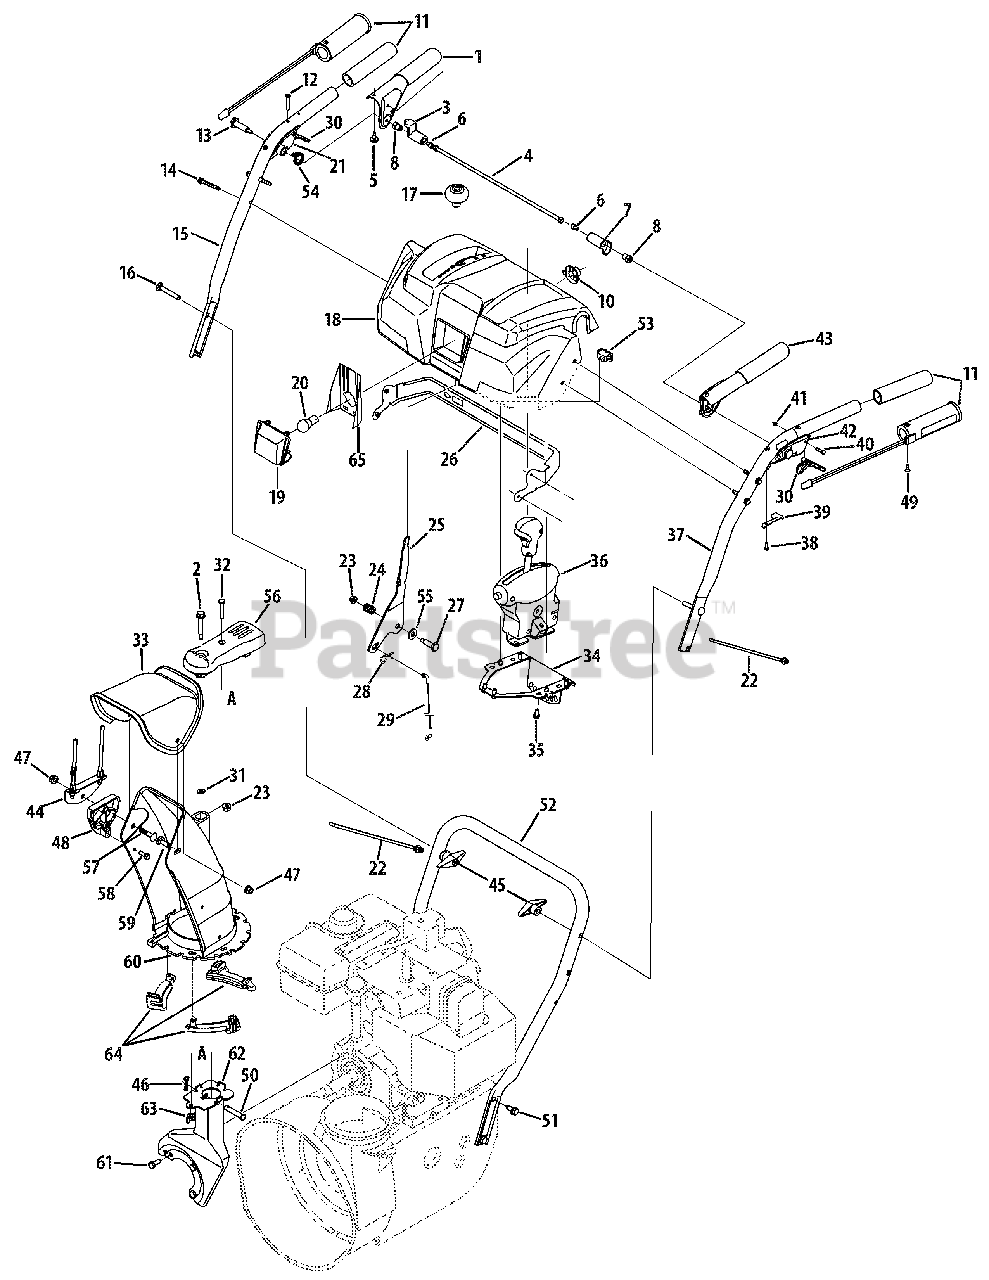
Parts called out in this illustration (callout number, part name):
1	Handle Engagement Assembly RH
2	Flange Shoulder Screw
3	Lock Plate
5	Rubber Bumper
6	Screw, 1/4-20 x.375
7	Clutch Lock Cam
8	Shoulder Nut, 1/4-20
9	Wire Harness w/ Htd. Grip (NS)
10	Light Socket
11	Handle Grip
11	Heated Handle Grip
12	Screw, #10-24 x 0.375
13	Shoulder Screw, 1/4-20 x 1.345
14	Screw, 1/4-20 x 1.625
16	Carriage Screw, 5/16-18 x 2.25
17	Shift Knob
18	Handle Panel N-Style
20	Lamp
21	Handle Clutch Lock - RH
22	Cable Tie
23	Flange Lock Nut, 1/4-20
24	Compression Spring
27	Shoulder Screw
28	Click Pin
29	Speed Selector Cable
30	Steering Triggers
31	Flat Washer, .25 x .630 x .0515
32	Hex Screw, 1/4-20 x 1.50
33	Upper Chute
35	Hi-Lo Screw, 1/4-15 x 0.5
36	4-Way Chute Control
38	Screw, #8-16 x 0.50
39	Clutch Lock Spring
42	Handle Clutch Lock - LH
43	Handle Engagement Assembly LH
45	Wing Knob
46	Bow Tie Cotter Pin
47	Flange Lock Nut, 5/16-18
48	Chute Tilt Cable Guide
51	AB Screw, 5/16-18 x 0.750
53	Heated Grips Switch
54	Torsion Spring
55	Flat Washer .385 x .87 x .06
56	Joystick Pulley Cover
57	Carriage Bolt, 5/16-18 x 1.50
58	Hi-Lo Screw, 1/4-15 x .75
59	Carriage Bolt, 5/16-18 x 1.0
60	Lower Chute
61	Hex Screw, 5/16-24 x .750
64	Chute Flange Keeper
65	Lens Reector Label
